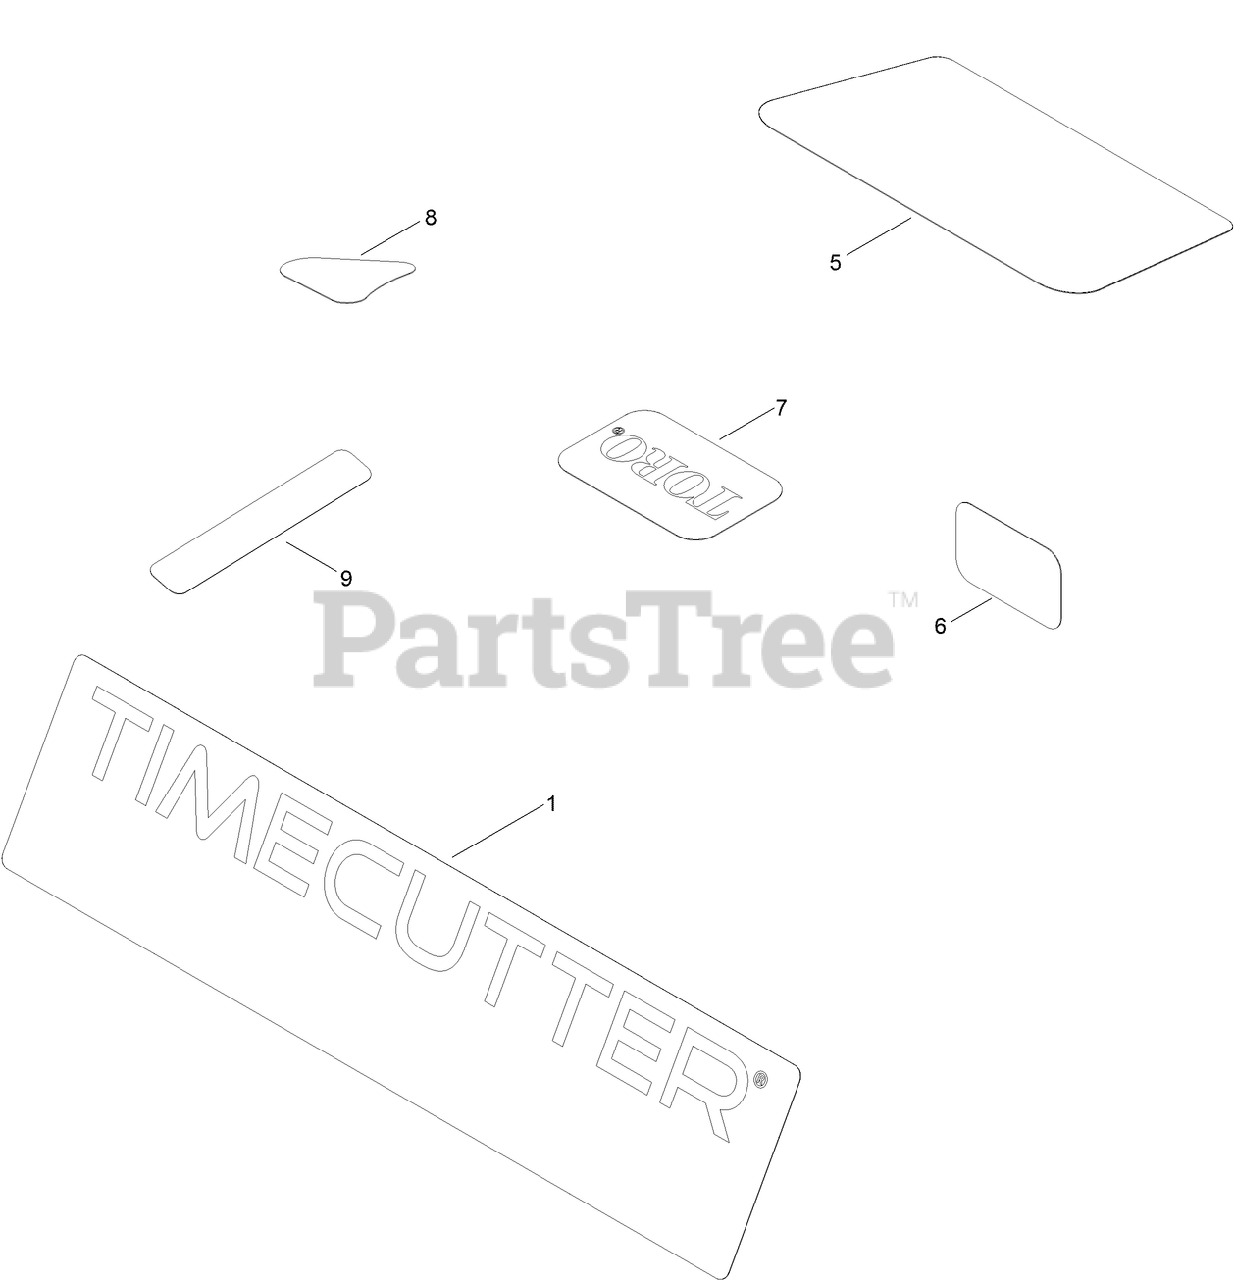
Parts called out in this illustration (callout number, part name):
1	DECAL-TIMECUTTER
5	DECAL-ENGINE
6	PLACARD-INTAKE
8	DECAL-DRAIN, OIL
9	DECAL-SHUTDOWN
